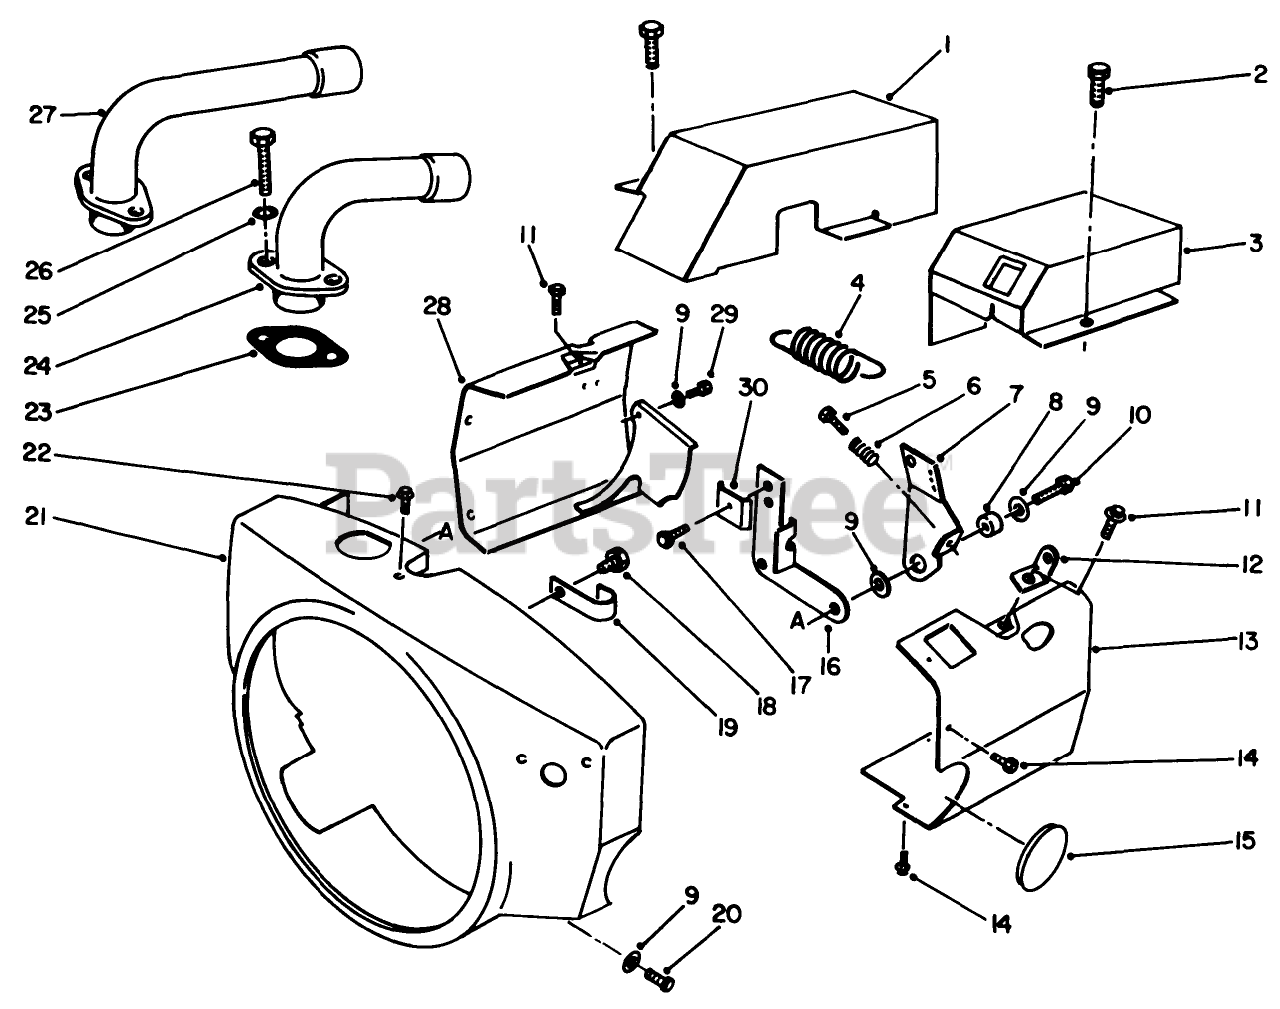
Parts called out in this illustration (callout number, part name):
1	LH EXHAUST TUBE COVERR
2	HX WSHR HD CAPSCREW
3	RH EXHAUST TUBE COVERR
4	SPRING
5	SCREW-TAP
6	SPRING
8	BUSHING
9	WASHER-FLAT
10	SCREW-HWH
11	SCREW-HHF
12	Bracket-Lift
13	CYL AIR HOUSING ASSY
14	SCREW-HWH
15	AIR SEAL GROMMET
16	BRACKET-GOVERNOR
17	SCREW-TAPPING
18	SCREW-HHF
19	CLIP-WIRE
20	SCREW-HH
21	Housing-Blower
22	HEX HD CAPSCREW
23	Gasket
24	EXHAUST TUBE
25	WASHER-FLAT
26	SCREW-HH
27	EXHAUST TUBE
28	Housing-L.H.
29	SCREW-HH
